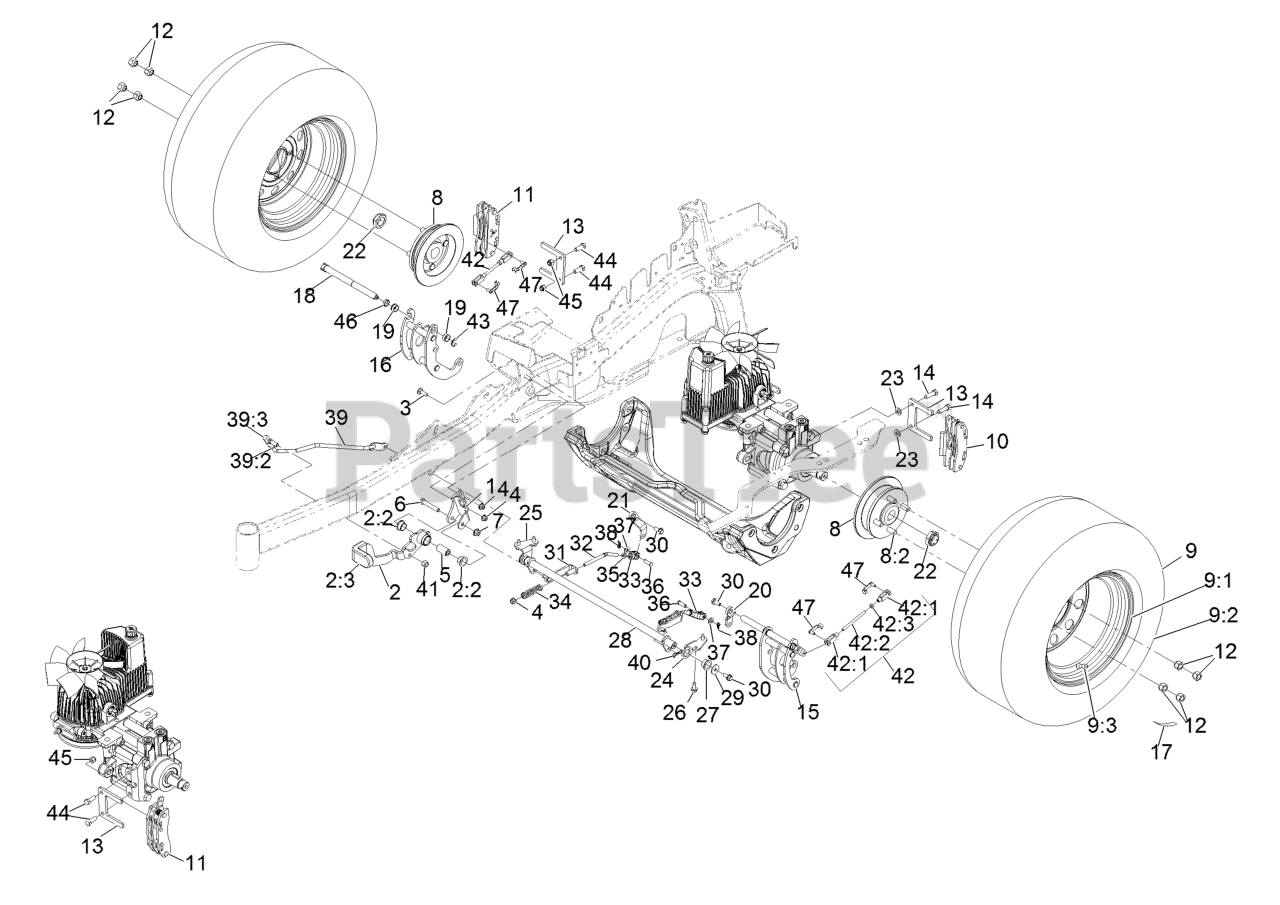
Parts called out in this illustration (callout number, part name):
1	BRACKET-MOUNT
2	BRAKE LEVER ASM W/ GRIP
2:2	BUSHING-FLANGE
2:3	GRIP-LEVER
3	BOLT-CARR
4	NUT-HF, NI
5	HANDLE-PIVOT, BRAKE
6	SCREW-HH
7	NUT-HF, NI
8	WHEEL HUB ASM
8:2	STUD-WHEEL
9	WHEEL AND TIRE ASM
9:1	ASM, RIM
9:2	TIRE-DRIVE, 23X9.5-12
9:3	Stem-Valve
10	CALIPER-BRAKE
11	CALIPER-BRAKE, RH
12	NUT-LUG
13	PLATE-MOUNT, BRAKE
14	SCREW-LOCK, PATCH
15	MOUNT-BELLCRANK, LH
16	MOUNT-BELLCRANK, RH
17	DECAL-TORQUE, WHEEL HUB LUG
18	BELLCRANK
19	BUSHING
20	ARM-INNER, LH
21	ARM-INNER, RH
22	LOCKNUT
23	WASHER-FLAT
24	MOUNT-PIVOT, LH
25	MOUNT-PIVOT, RH
26	Screw-HWH 5/16-18 X 3/4 Tf
27	BUSHING-FLANGE
28	SHAFT-CROSS
29	WASHER-FLAT
30	SCREW-HHF
31	BRACKET-L
32	LINKAGE-MID
33	YOKE-OFFSET
34	SPRING-COMPRESSION
35	NUT-JAM
36	PIN-CLEVIS
37	WASHER-PLAIN
38	PIN-COTTER, LOCKING
39	FRONT LINKAGE ASM
39:2	END-TIE ROD, RH
39:3	NUT-HJ
40	PIN-COTTER, LOCKING
41	NUT-LOCK
42	REAR LINKAGE ASM
42:3	NUT-JAM
44	SCREW-HH
45	NUT-LOCK, NI
47	PIN-CLEVIS, SPRING
